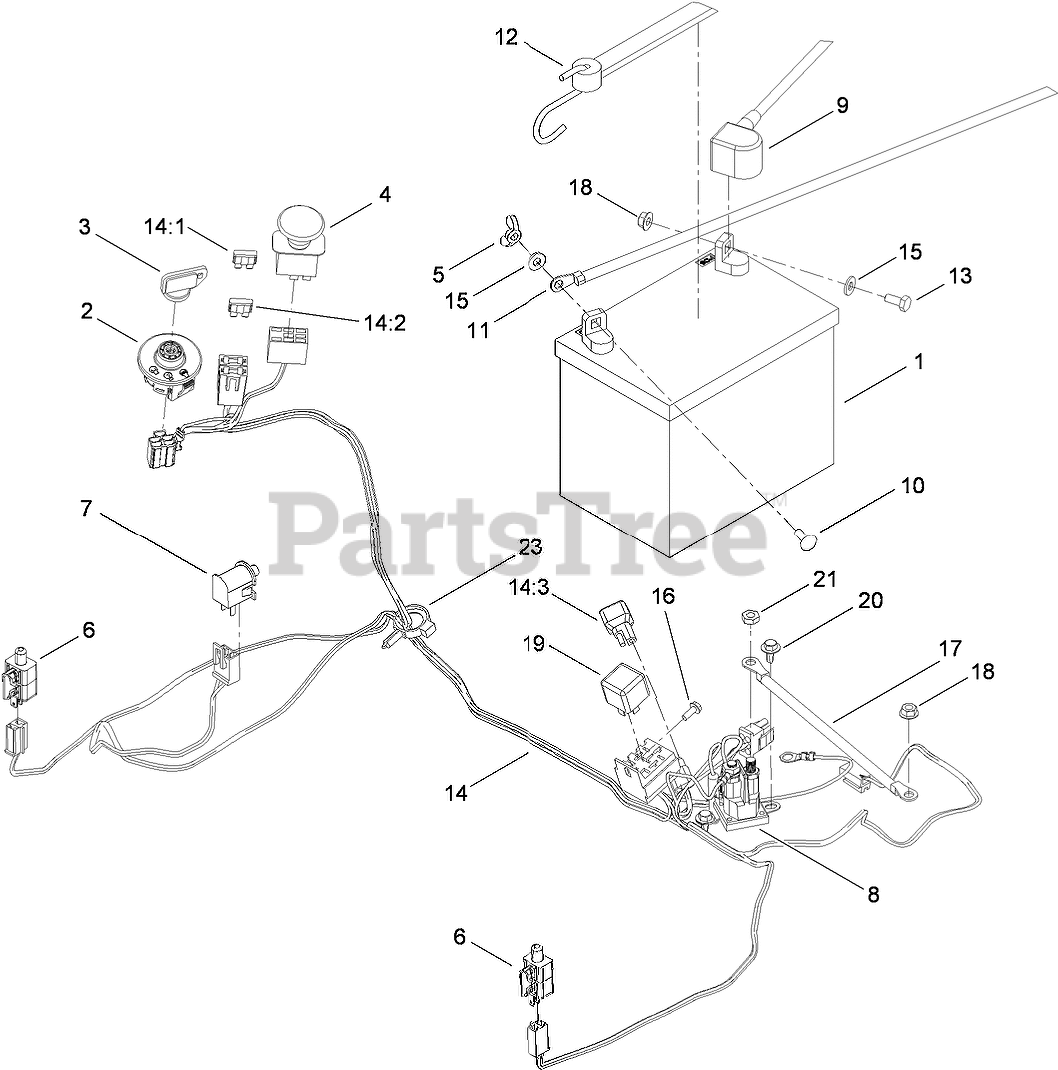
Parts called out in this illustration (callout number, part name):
1	BATTERY
2	SWITCH-IGNITION
3	KEY-IGNITION
4	SWITCH-PTO
5	NUT-WING
6	SWITCH
7	SWITCH-BAIL
8	SOLENOID
9	CABLE-BATTERY, RED
10	BOLT-CARR
11	CABLE-BATTERY, BLACK
12	HOLDDOWN-BATTERY
13	SCREW-HH
14	HARNESS-WIRE
14:1	FUSE-BLADE, 30 AMP
14:2	FUSE-BLADE, 25 AMP
15	WASHER-FLAT
16	SCREW-TAPTITE
17	CABLE-BATTERY, RED
18	NUT-HF
19	RELAY
20	SCREW-HHFTF
21	NUT-JAM
23	CLAMP-HOSE
